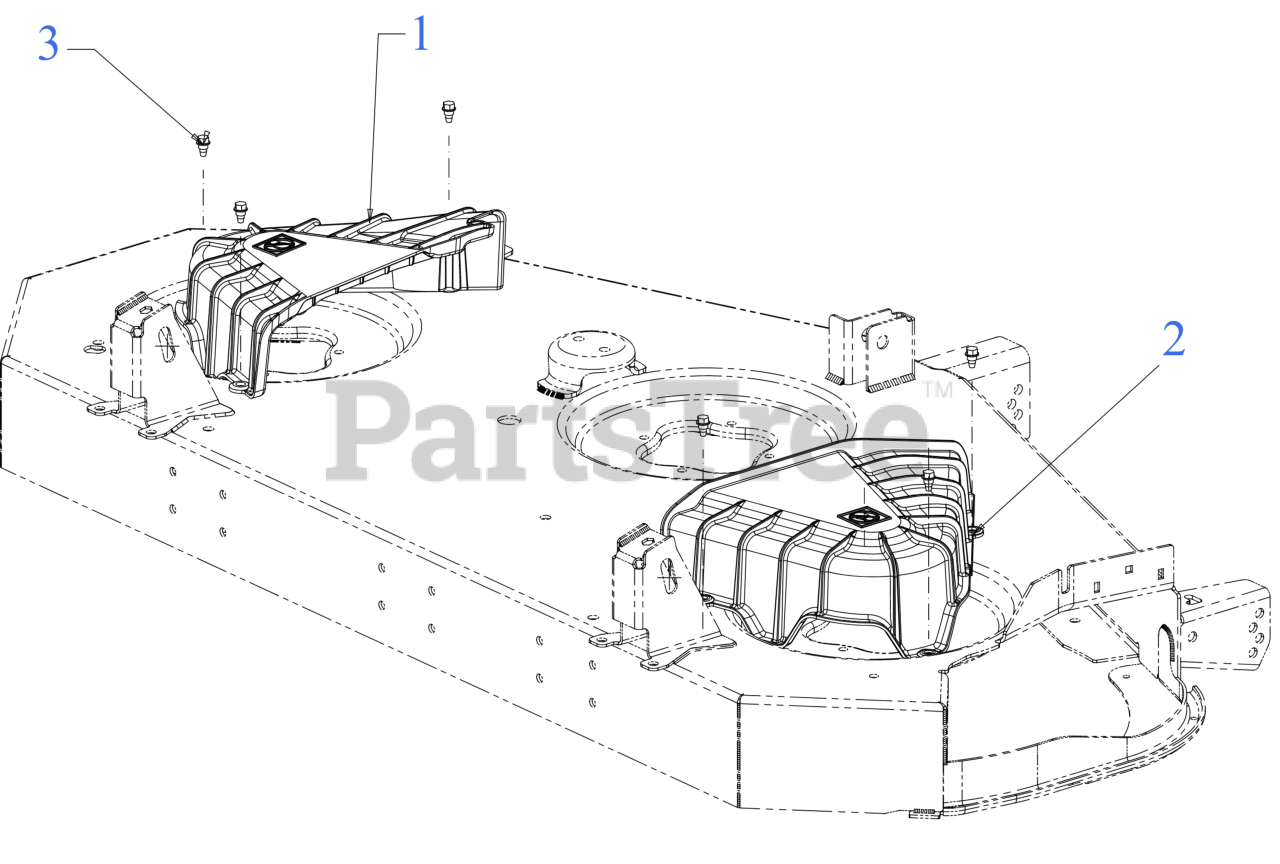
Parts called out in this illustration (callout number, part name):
1	SPINDLE COVER (LH)
2	SPINDLE COVER (RH)
3	SHOULDER SCREW 1/4-20 x .50
